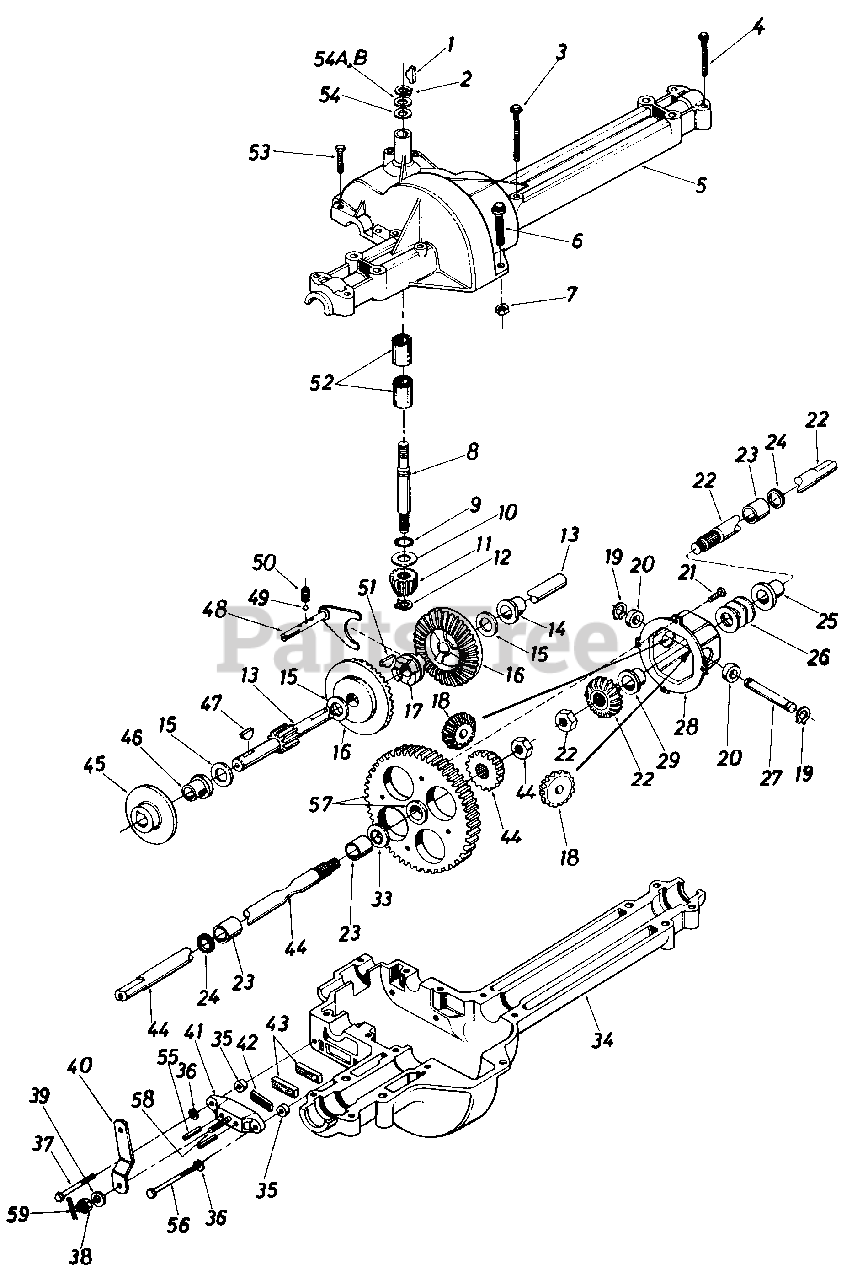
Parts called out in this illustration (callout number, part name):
1	#4 Hi-Pro Key 3/32 x 5/8" Dia.
2	Snap Ring .625" Shaft
3	Hex Bolt 1/4-20 x 1.75" Lg.
4	Hex Bolt 5/16-18 x 2.5"
5	Upper Housing
6	Hex R-Bolt 20 x .88" Lg.
7	Hex Nut 1/4-20 Thd.
8	Input Shaft
9	Square Seal 5/8" l.D.
10	Thrust Washer 5/8 I.D. x 1.25 O.D.
11	Pinion Input 14T
12	Retaining Ring 7/16" Ext.
14	Flange Brg. 5/8" l.D. x 3/4" Lg.
15	Fl-Wash.
16	Bevel Gear 42T
17	Clutch Collar
18	Miter Gear 15T (H.D.)
19	Snap Ring
20	Thrust Bearing 1/2" I.D. x 1.0" O.D.
21	Pan Head Scr. 1/4-20 x .50" Lg. w/Patch
22	Axle R.H. Ass'y.-Kit
23	Sleeve Bearing 3b" I.D. x 1 on Lg
24	Oil Seal 3/4 l.D.
25	Flange Bearing 3/4 l.D. x 15/16 Lg.
26	Fl-Wash. .760" l.D. x 1.49" O.D.
27	Cross Shaft
28	Differential Housing Ass'y.
33	Fl-Wash. .760" l.D. x 1.49" O.D.
34	Lower Housing
35	Spacer 53" O.D. x 3/8" Lg.
36	L-Wash. 1/4" l.D.
37	Hex Bolt l/4-20 x 1.50" Lg. (Grade 5)
38	Castle Nut 5/16-24 Thd.
39	Fl-Wash. .344" I.D. x .875" O.D.
40	Actuating Arm
42	Puck Plate
43	Brake Puck
44	Axle L.H. Ass'y.-Kit
46	Flange Bearing 5/8" I.D. x 15/16" Lg.
47	Woodruff Key 3/16 x 5/8 HT
48	ShiR Fork Ass'y.
49	Ball Detent .250" Dia.
50	Spring Detent
51	#9 Hi-Pro Key 3/16" x 3/4" Dia. HT
52	Needle Brg. 5/8" l.D. x 1/2" Lg.
53	Hex Bolt 1/4-20 x 1.00" Lg.
54	Fl-Wash. 5/8" I.D. x .030
54A	Fl-Wash. 5/8" I.D. x .040
55	Actuating Pin 5/16" Dia.
56	Hex Bolt 1/4-20 x 2.50" Lg. (Grade 5)
57	Differential Gear 72T Ass'y. w/Bearing
58	Sq. Hd. Bolt 5/16-24 Thd.
59	Cotter Pin 3/32" Dia. x .50" Lg.
